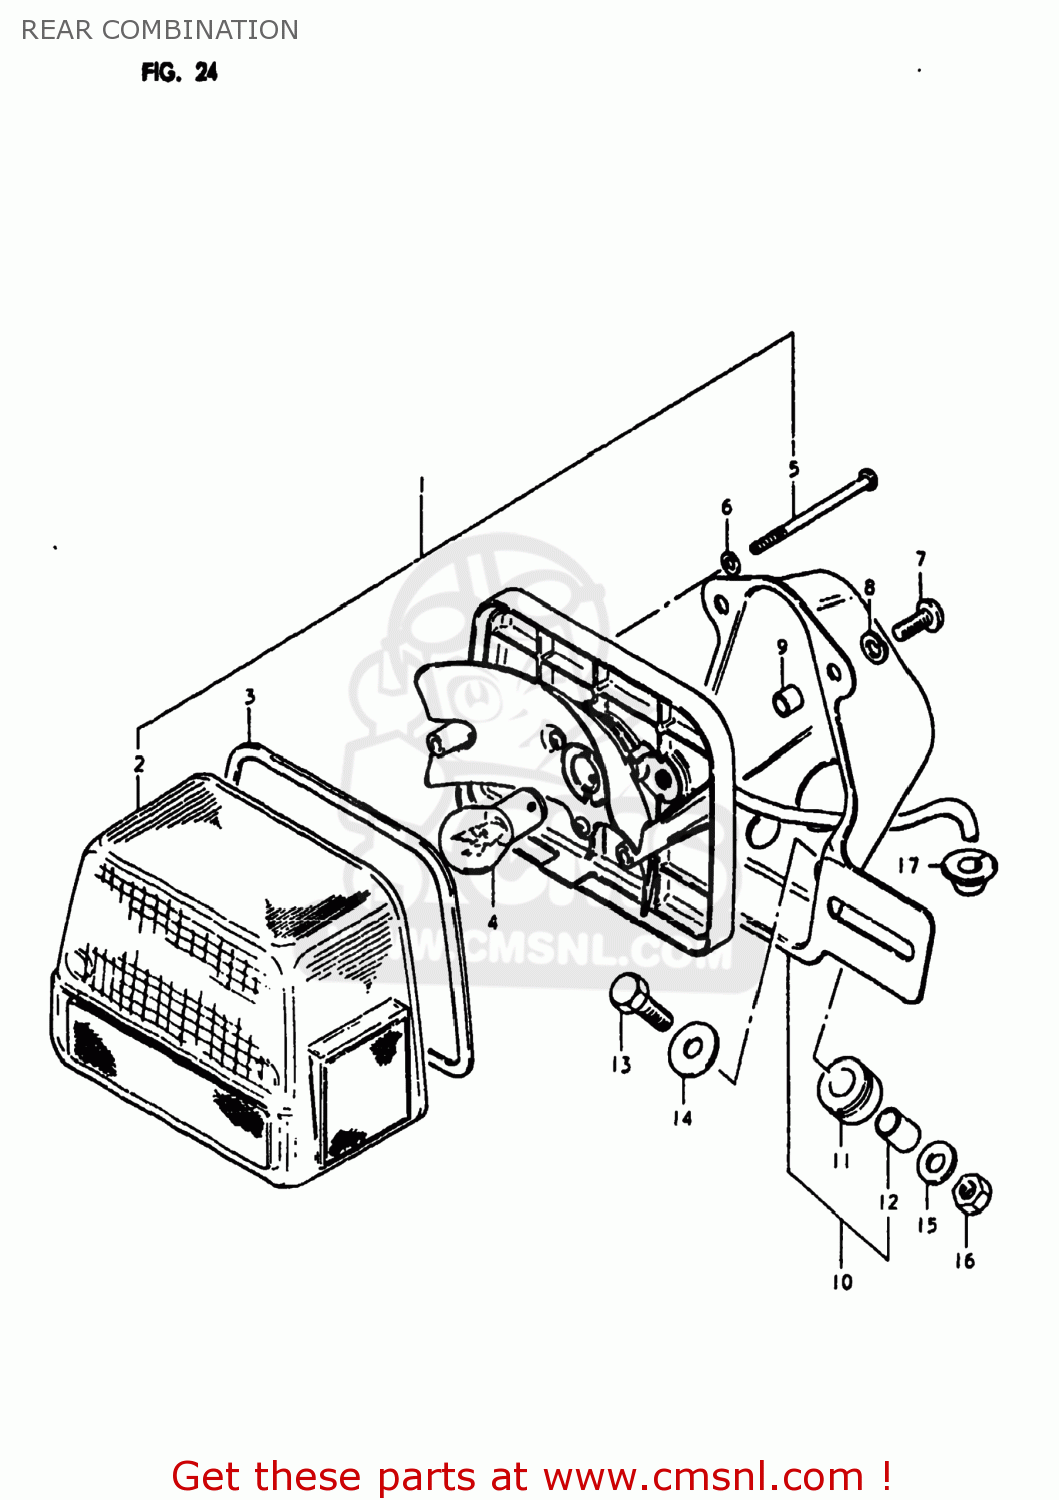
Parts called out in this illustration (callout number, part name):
1	LAMP UNIT,REAR COMBINATION
2	LENS
3	GASKET (NAS)
4	BULB(12V23W)
5	SCREW
6	GASKET (NAS)
7	SCREW
8	LOCK WASHER
9	SPACER
10	BRACKET UNIT,TAIL LAMP
11	CUSHION
12	SPACER
13	BOLT
14	WASHER (6.5X20X1.2)
15	WASHER
16	NUT
17	GROMMET
